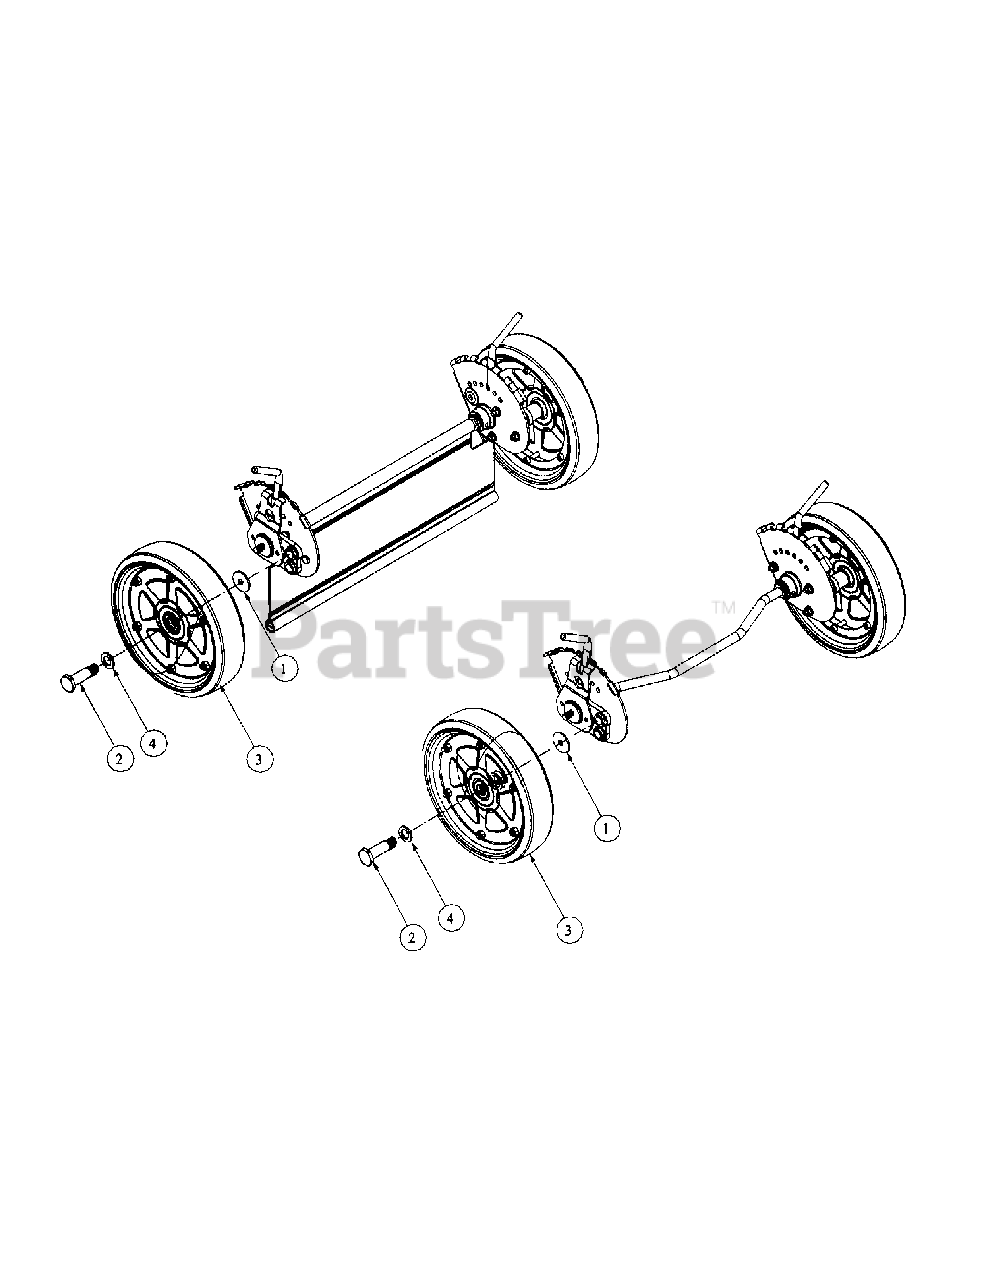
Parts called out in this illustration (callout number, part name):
1	Washer, 1/2 x 1 Shim
2	Shoulder Screw, .58 x 1.48, 1/2-20
3	Wheel, 9 x 2.125
4	Shim Washer, .625 x .875 x .031
